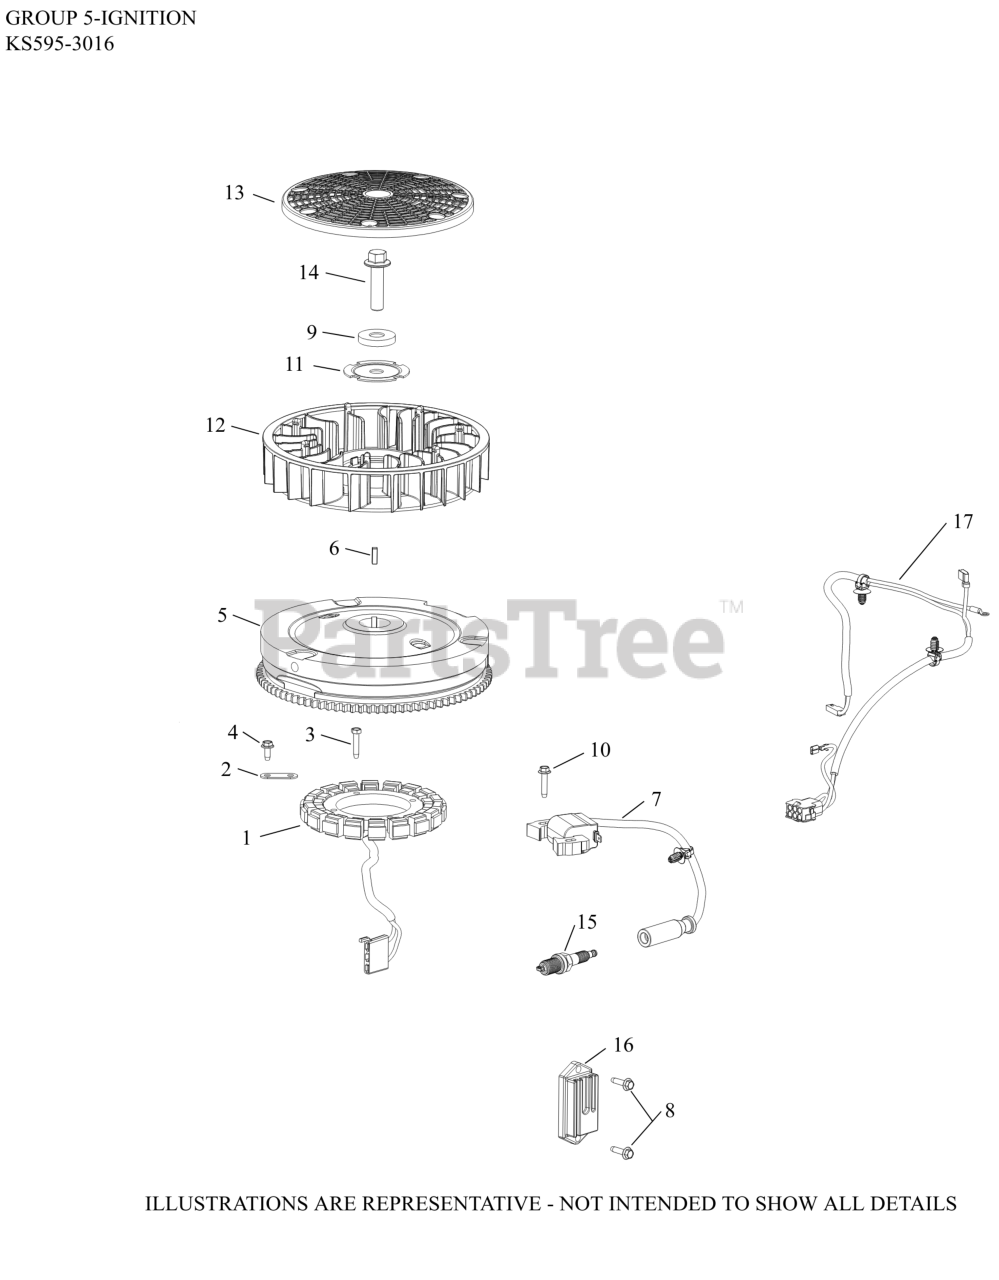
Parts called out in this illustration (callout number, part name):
1	STATOR ASSY, 12A
2	CLIP, STATOR WIRE
3	SCREW, THREAD FORMING
4	SCREW, FLG THD FRM M5X0.8X13
5	FLYWHEEL, ASSY
6	KEY, SQUARE
7	MODULE, INDUCTIVE IGNITION COIL
8	SCREW, THD FRM-USE 25 086 473-S
9	WASHER, FLAT
10	SCREW, THREAD FORMING
11	PLATE, FAN MOUNTING
13	SCREEN, GRASS
14	SCREW, HEX FLANGE
15	PLUG, SPARK
16	REGULATOR/RECTIFIER 12/15A HALF-WAVE STD
17	HARNESS, WIRING NON-OSU, MTD
